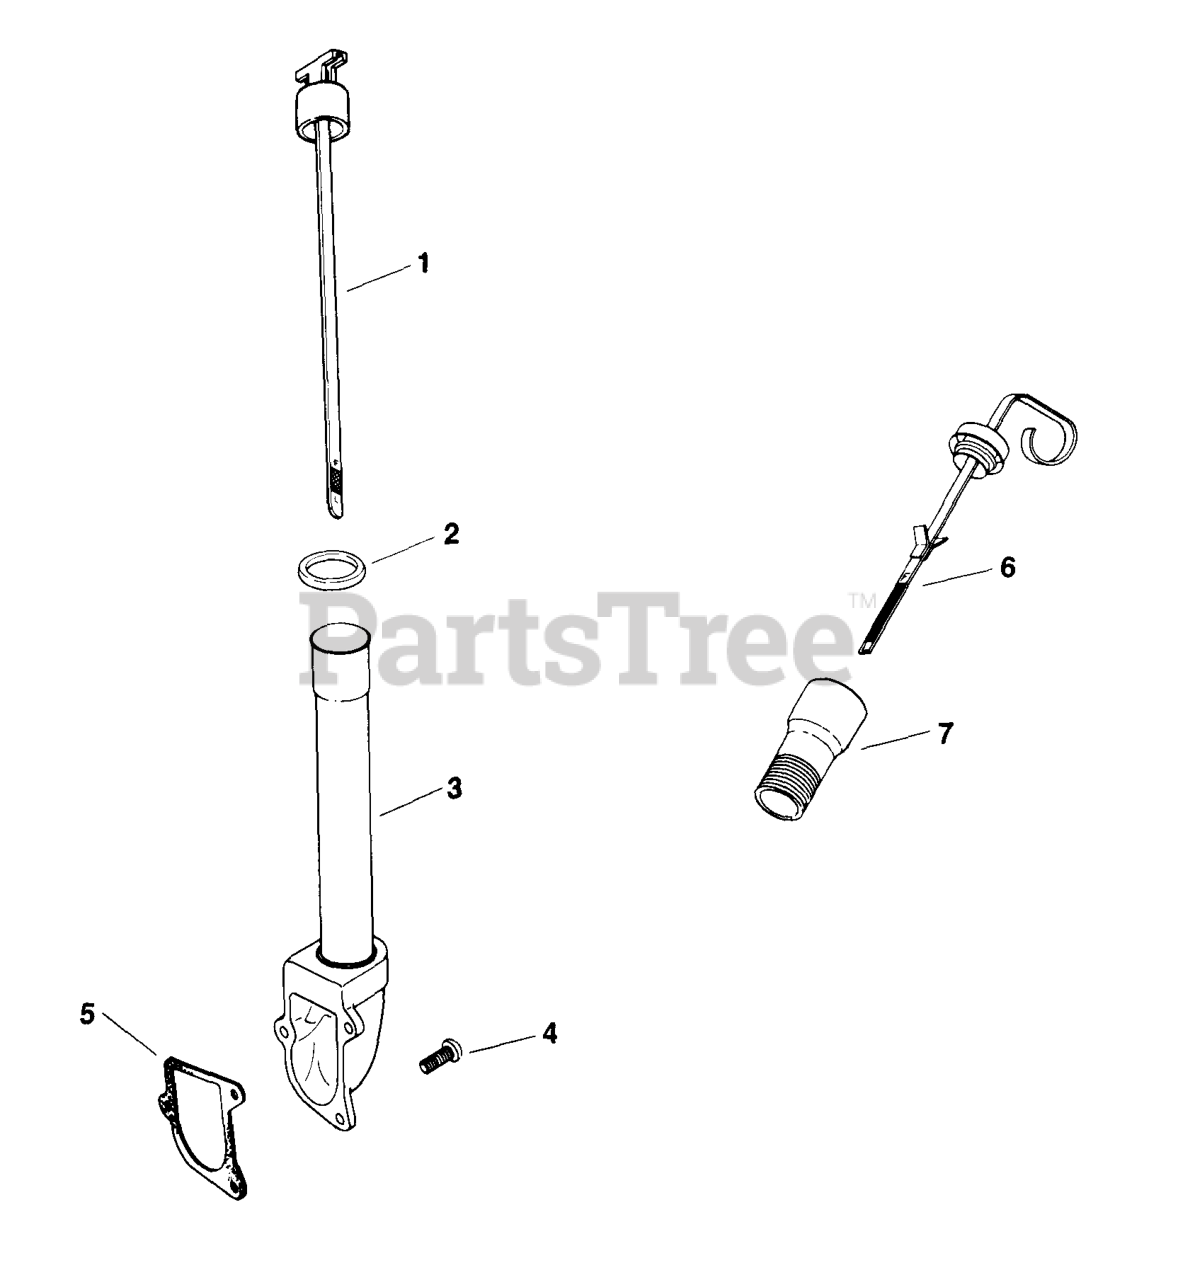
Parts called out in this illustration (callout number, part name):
1	DIPSTICK - DISCONTINUED
4	SCREW - DISCONTINUED
5	GASKET, OIL FILL ADAPTER
